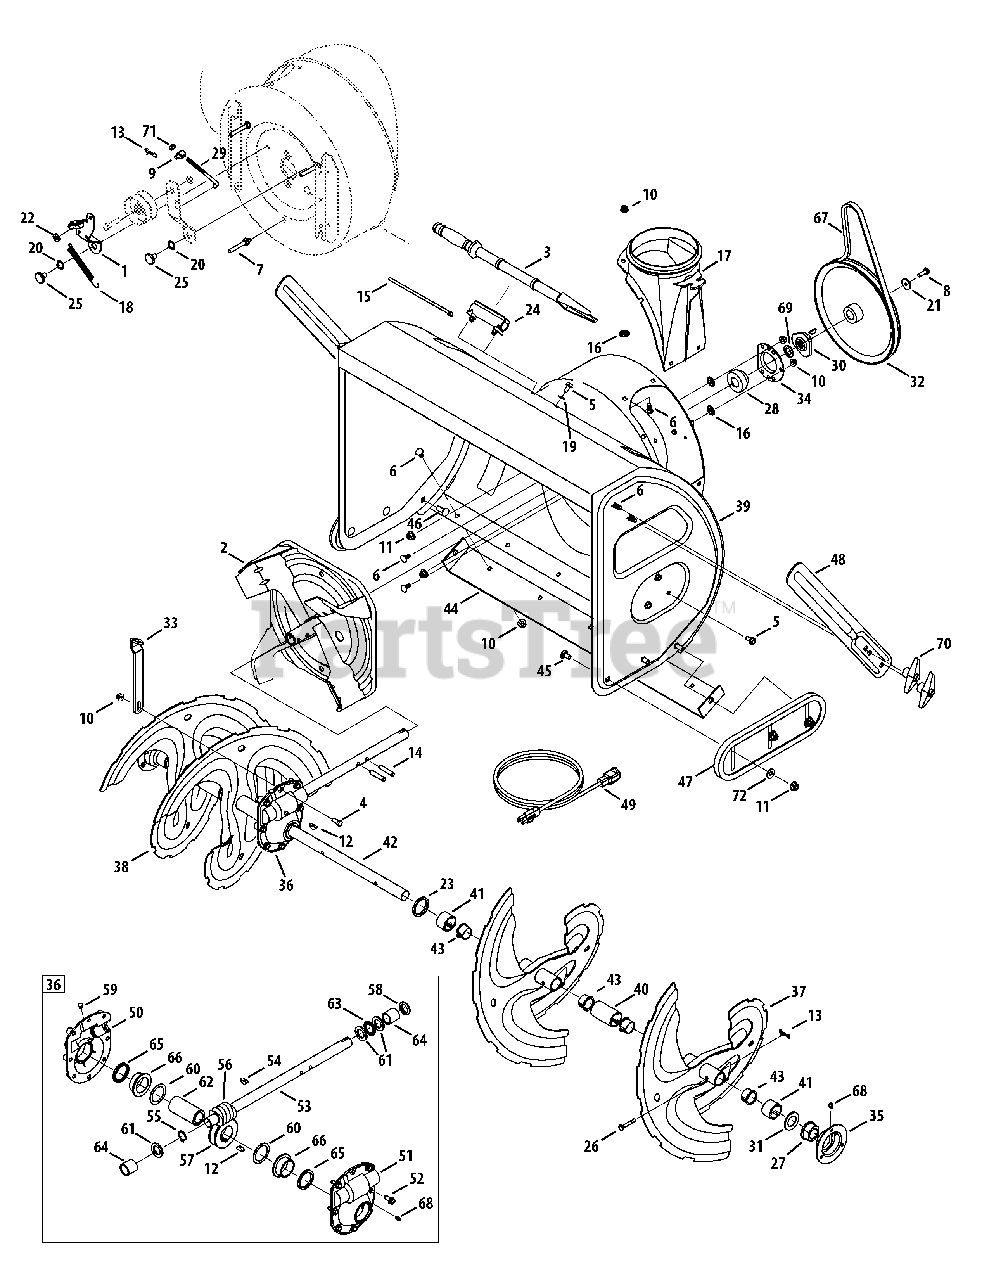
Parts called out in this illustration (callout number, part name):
1	Bracket Assy, Auger Brake
2	Impeller, 16"
3	Tool, Cleanout
4	Scr,Hex Cap, 5/16-18 x 1.00
5	Screw, 5/16-18 x .750
6	Screw, Carriage, 5/16-18 x .75
7	Screw, 5/16-18 x .4300
8	Screw, 5/16-24 x .875
9	Ferrule
10	Nut, Flnge Lk, 5/16-18
11	Nut, Flg Lk, 3/8-16
12	Key, Woodruff,1/4 x 3/4
13	Pin, Bowtie Cotter
14	Pin, Spirol, 5/16 x 1.75
15	Tie, Cable
16	Nut, Push
17	Adapter, Chute, 6"
18	Spring, Extension
19	Washer, .349 x .879 x .063
20	Washer, .625 x .885 x .015
21	Washer, Flat, .34 x 1.50 x .150
22	Washer, .344 x .75 x .12
23	Washer, 1.01 x 1.86 x .06
24	Clip, Mounting
25	Screw, Shoulder, .625 x .17
26	Pin, Shear, .25 x 1.75
27	Bearing, Flange w/Flats
28	Bearing, Self Aligning
29	Rod, Auger Idler
30	Pulley, Adapter, .75 Dia.
31	Spacer, 1.004 x 1.375 x .25
32	Pulley, Auger Drive, 10.0
33	Bracket, Gear Box Support
34	Housing, Bearing
35	Housing, Bearing
36	Gear Box Assembly, Auger
37	Spiral Assy, LH
38	Spiral Assy, RH
39	Housing, Auger - 33"
40	Spacer, 1.0 x 1.5 x 2
41	Spacer, 1.0 x 1.5 x 1
42	Axle, Spiral, 33"
43	Bushing, Flange, 1.051 x 1.16
44	Shave Plate
45	Bolt, Carriage, 3/8-16 x 1.0
46	Bolt, Carriage, 3/8-16 x 1.25
47	Shoe, Skid
48	Drift Cutter
49	Extension Cord, 110V
50	Hsg Assy Auger RH (Inc. 65 & 66)
51	Hsg Assy Auger LH (Inc. 65 & 66)
52	Screw, LD, 5/16-18 x .750
53	Shf, Drive, Auger
54	Key, Hi Pro, 3/16 x 3/4
55	Ext, Ret, Ring
56	Gear, Worm, Dbl Thread
57	Gear, Worm, LH
58	Seal, Oil
60	Washer, Flat, 1.52 ID x 2.0 OD
61	Washer, Flat, .88 ID x .38 OD
62	Shf, Gear, Worm
63	Brg, Thrust
64	Sleeve
65	Oil Seal
66	Flange Bearing
67	V Belt,4L x 44.60 Lg.
68	Lube Fitting, 3/16 #70
69	Washer, Flat, .78 x 1.49 x .08
70	Wing Knob
71	Jam Nut, 5/16-18
72	Washer, Flat, .385 x .870
